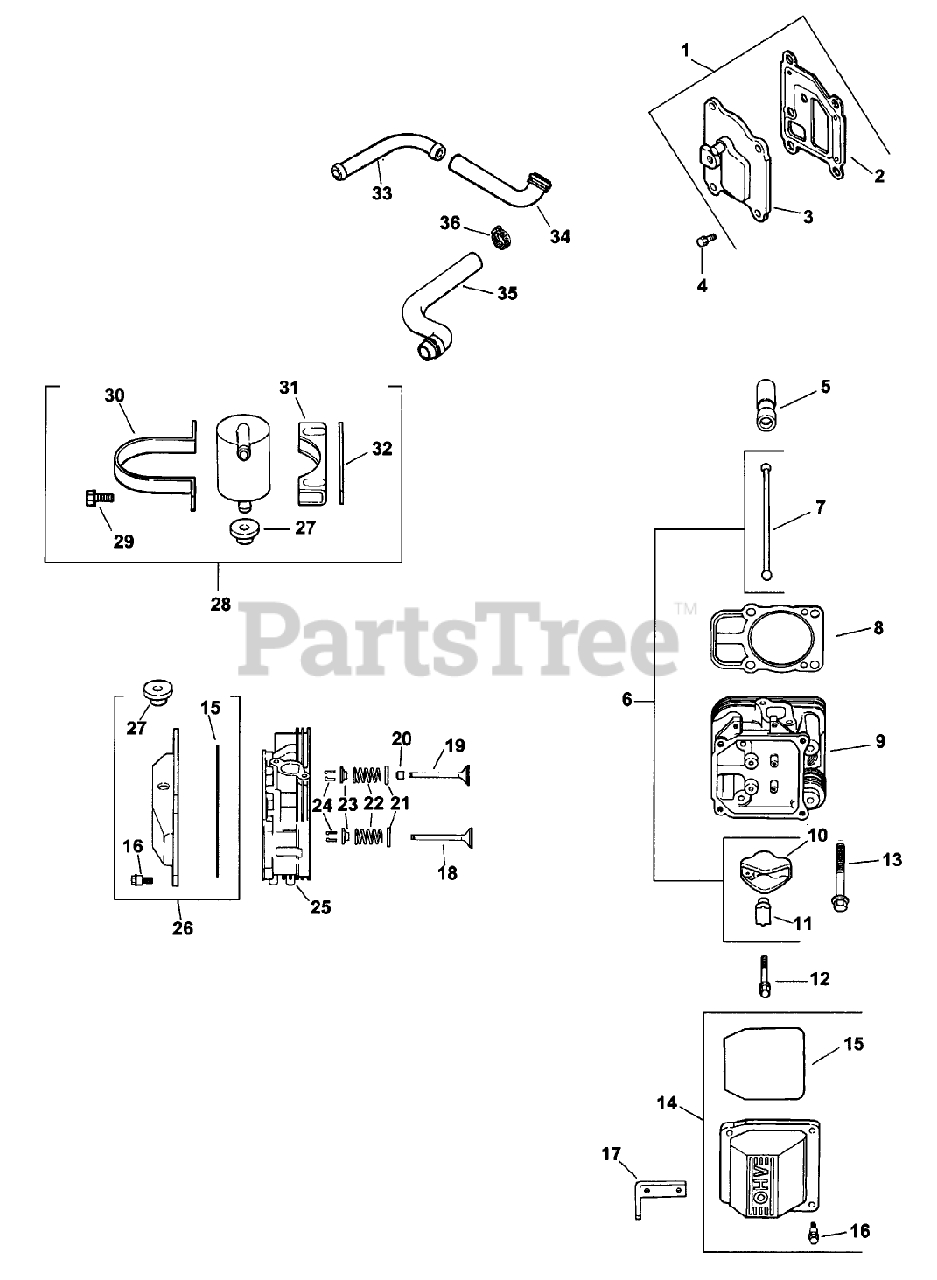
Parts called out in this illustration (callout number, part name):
1	Kit, breather cover w/gasket (Incl. 2, 3)
2	Gasket-Breather
3	Cover, breather
4	Screw
5	Lifter-Valve
6	Kit, valve train (Includes 7, 10, 11)
7	Rod-Push
8	Gasket-Cylinder Head
9	#2 Cyl. Head Asm,
10	Arm-Rocker
11	Pivot-Arm, Rocker
12	Screw
13	Screw
14	Kit, valve cover-plain (Includes 15, 16)
15	O-Ring
16	Screw
17	Strap-Lifting
18	Valve-Exhaust
19	Valve-Intake
20	Seal-Stem, Valve
21	Retainer-Spring
22	Spring-Valve
23	Cap-Spring, Valve
24	Retainer Kit
25	#1 Cyl. Head Asm
26	Kit,valve cover breather(Incl. 15, 16, 27)
27	Grommet-Rubber
28	Kit, breather separator (Includes 27, 29-32)
29	Screw-HF
30	Strap-Lifting
31	Bracket
32	Spacer
33	Fitting
34	Hose-Breather
35	Hose-Breather
36	Clamp
